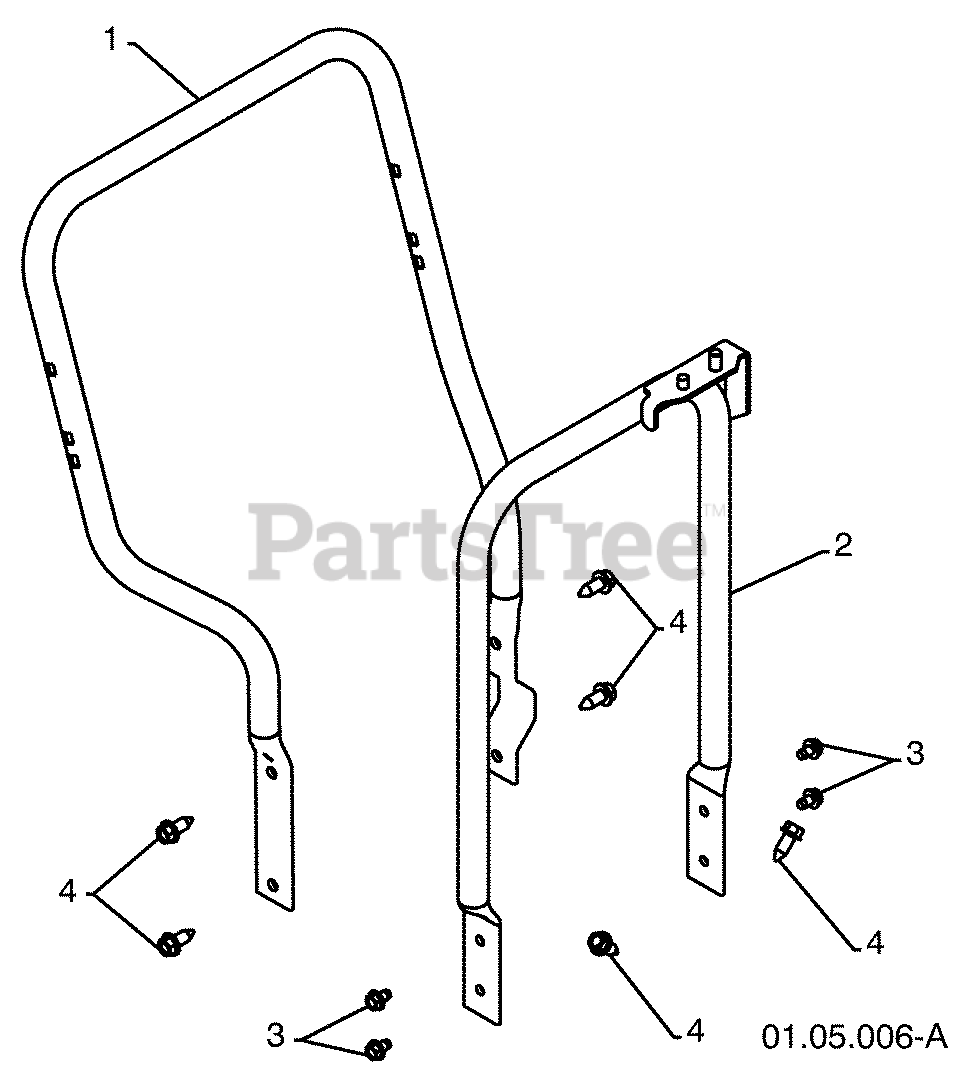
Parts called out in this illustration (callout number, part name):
1	LOWER TUBE GRAY
2	PIVOT SUPPORT
3	BOLT 5/16-18 X .75
4	SCREW 3/8-16 X 1.00
